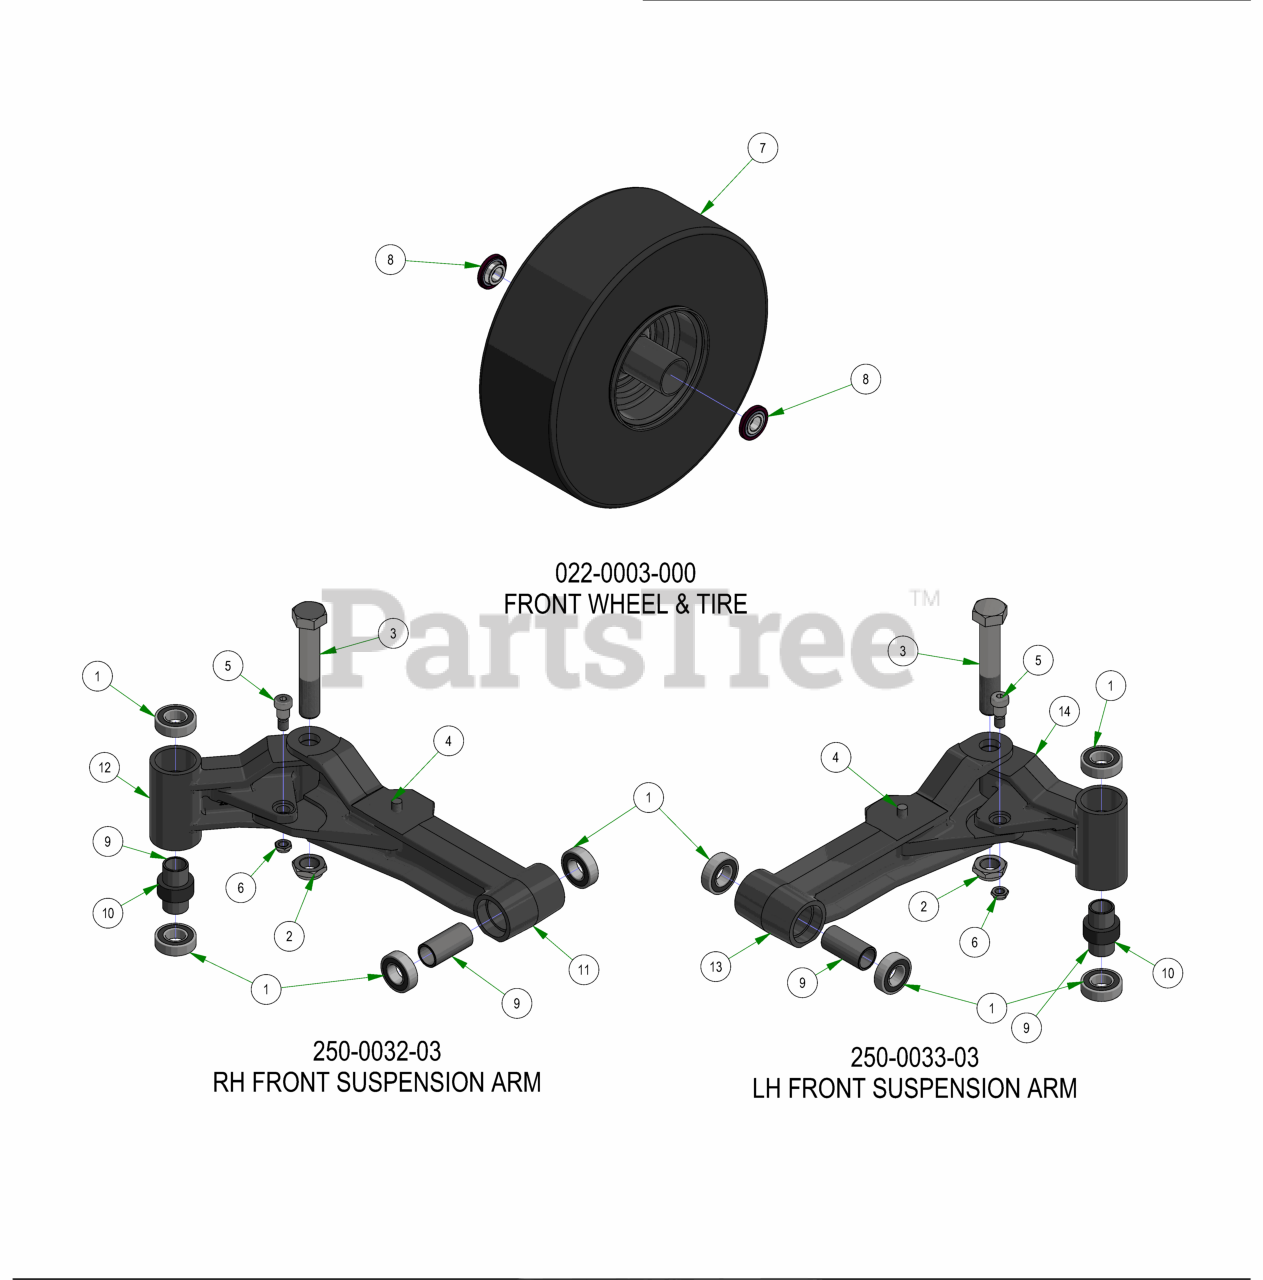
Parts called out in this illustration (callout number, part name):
1	1641 BEARING W/2 CONTACT RUBBER SEALS
2	1"-14 NYLON INSERT JAM LOCKNUT ZINC
3	1"-14 X 5-1/2 HEX CAP SCREW (GR.8) ZINC YELLOW
4	1/2-13 x 1" Stud
5	5/8 X 5/8 SOCKET SHOULDER BOLT ZINC YELLOW
6	1/2-13 NYLON INSERT JAM LOCKNUT ZINC
7	15x6-6 Tire Only
8	1-3/4" Bearing-Large Bore Front Rim
9	2016 Front Bearing Spacer
10	Rubber Stabilizer (Front Forks) [R series]
11	INNER RH FRONT AXLE
12	OUTER FRONT ARM RH
13	INNER FRONT ARM LH
14	CAST OUTER ARM LH
